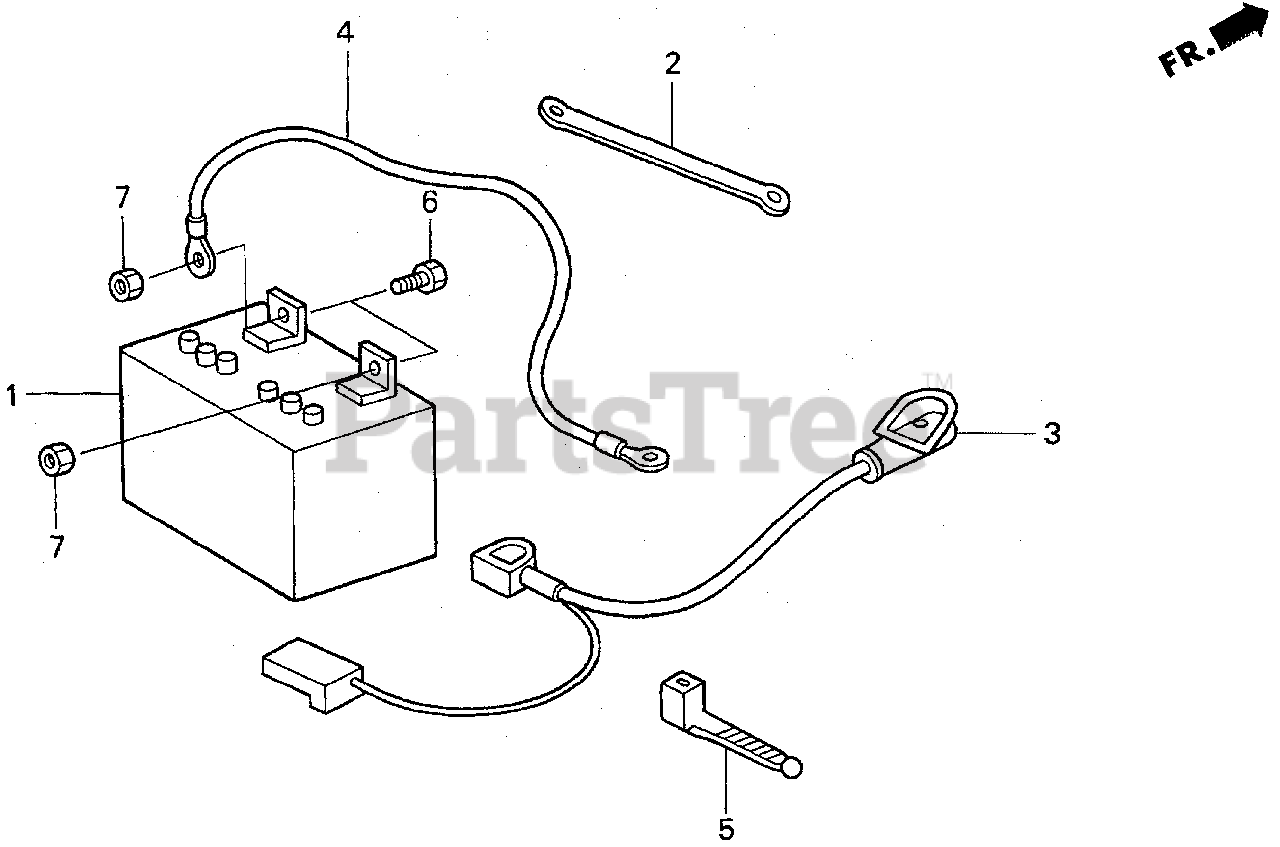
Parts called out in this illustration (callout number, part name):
1	BATTERY ASSY.
2	STRAP, BATTERY SETTING
3	CABLE ASSY., BATTERY
4	CABLE ASSY., GROUND
5	TIE, CABLE
6	BOLT, CARRIAGE (8X16)
7	NUT, FLANGE (8MM)
